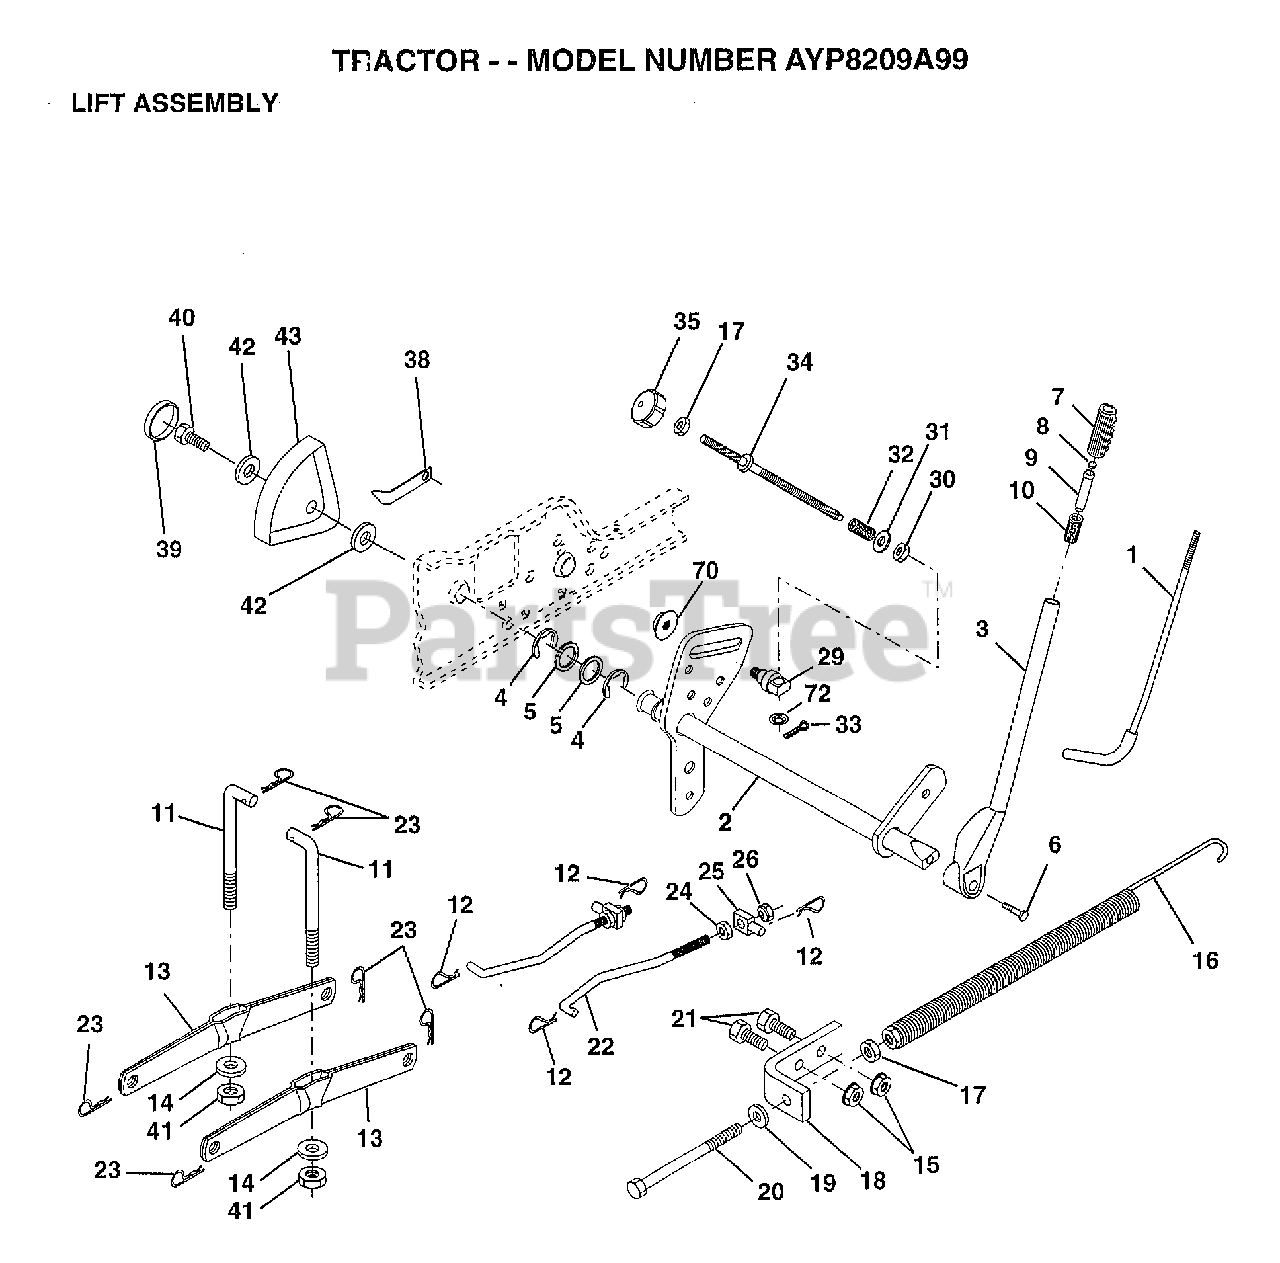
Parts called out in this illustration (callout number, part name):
1	LEVER ROD LT
2	SHAFT.ASM.LIFT.VGT
3	LEVER.ASM.LIFT.RH
5	WASHER
6	"BOLT,HEX"
7	GRIP HANDLE
10	SPRING T
11	LINK.LIFT.MWR.VGT
12	RETAINER SPRING
13	ARM SUSP REAR
14	BEARING PVT LH
17	NUT
18	BRACKET SPRING AS
19	WASHER
20	BOLT-ADJ SPRING T
21	BOLT
22	LINK.FRONT
24	NUT
25	TRUNION
26	NUT.LK.W/WSH.1/2.
29	TRUNNION
30	NUT T
31	WASHER
32	SPRING.COMP.INF.H
34	ROD.ADJ.LIFT
35	KNOB INF 3/8-16
38	POINTER-INDICAT
39	"PLUG,HOLE"
40	SCREW
41	NUT.CROWNLOCK.3/8
42	WASHER
43	HEIGHT INDICATOR
70	NUT.HXFLG.LOCK.
72	NUT PUSH M
